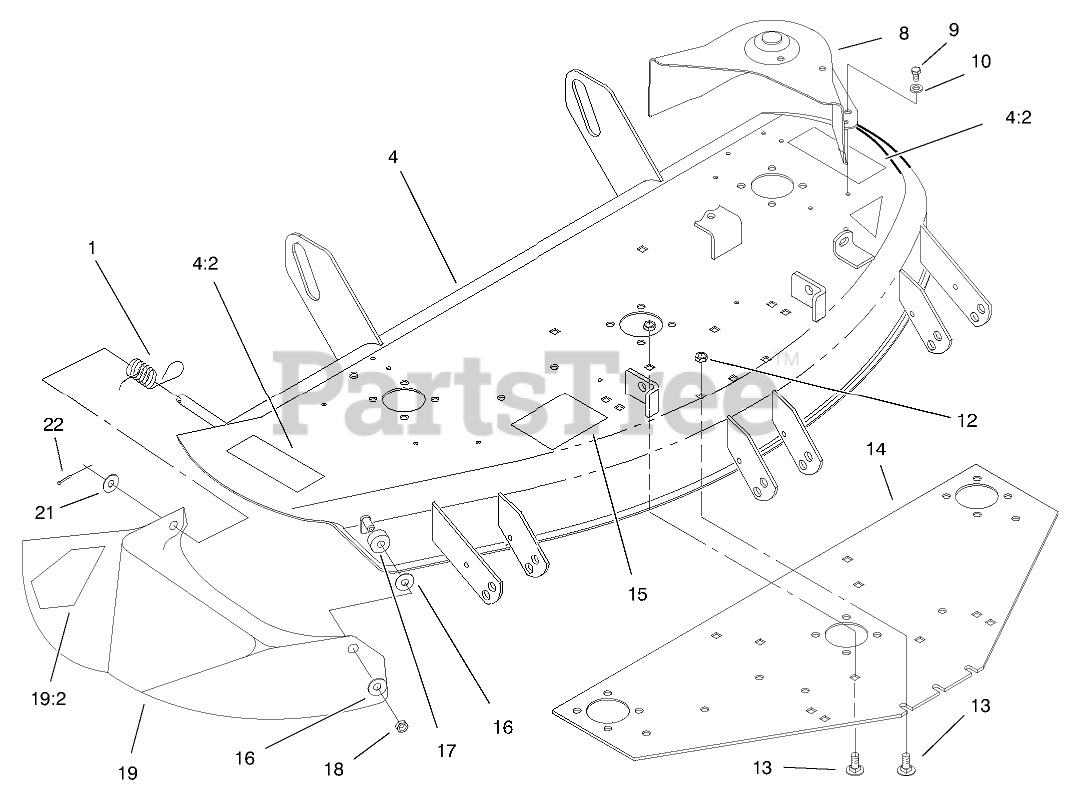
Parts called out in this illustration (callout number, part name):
1	SPRING-DEFLECTOR
4	DECK ASM
4:2	DECAL-DANGER
8	COVER-BELT
9	SCREW-HWH
10	WASHER-FLAT
12	NUT-LOCK, NI
13	SCREW-CARR
14	PLATE-DECK
15	DECAL-BELT INSTALL
16	WASHER
17	BUSHING-PIVOT
18	NUT-HJ
19	CHUTE ASM
19:2	DECAL-DANGER
21	WASHER-FLAT
22	PIN-COTTER
